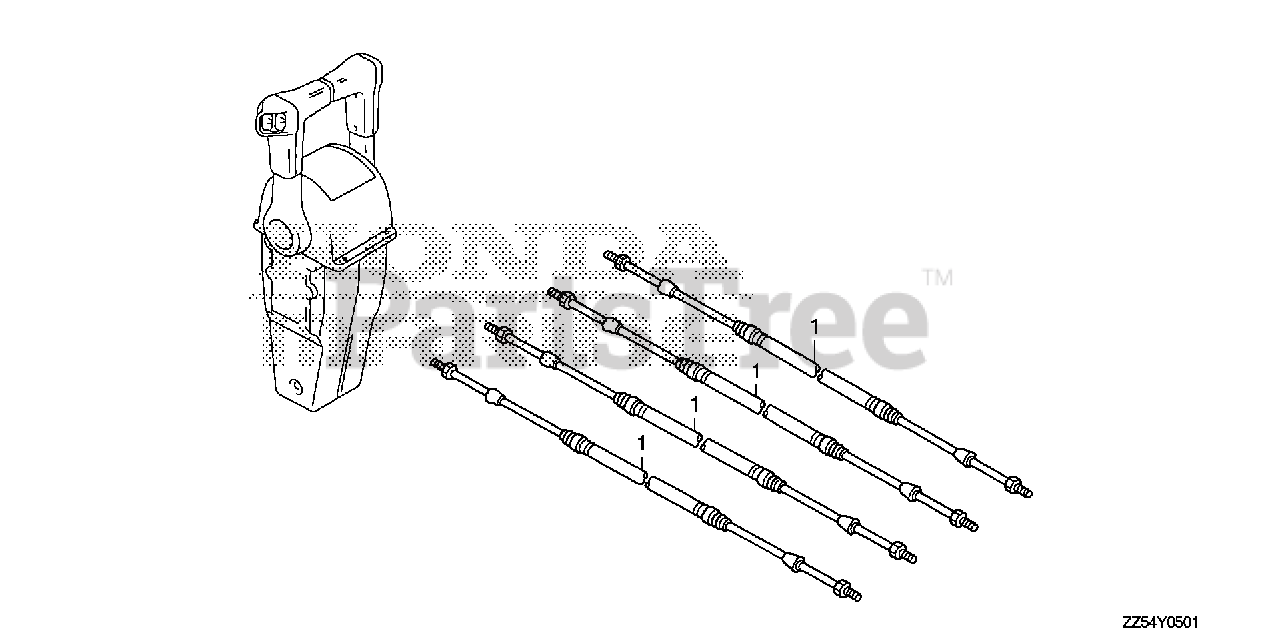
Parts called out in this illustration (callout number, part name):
1	CABLE, REMOTE CONTROL (10') (LOW FRICTION)
1	CABLE ASSY., PUSH-PULL (33C-5FT)
1	CABLE, REMOTE CONTROL (11') (LOW FRICTION)
1	CABLE ASSY., PUSH-PULL (33C-6FT)
1	CABLE, REMOTE CONTROL (12') (LOW FRICTION)
1	CABLE ASSY., PUSH-PULL (33C-7FT)
1	CABLE, REMOTE CONTROL (13') (LOW FRICTION)
1	CABLE ASSY., PUSH-PULL (33C-8FT)
1	CABLE, REMOTE CONTROL (14') (LOW FRICTION)
1	CABLE ASSY., PUSH-PULL (33C-9FT)
1	CABLE, REMOTE CONTROL (15') (LOW FRICTION)
1	CABLE ASSY., PUSH-PULL (33C-10FT)
1	CABLE, REMOTE CONTROL (16') (LOW FRICTION) (NOT AVAILABLE)
1	CABLE ASSY., PUSH-PULL (33C-11FT)
1	CABLE, REMOTE CONTROL (17') (LOW FRICTION)
1	CABLE ASSY., PUSH-PULL (33C-12FT)
1	CABLE, REMOTE CONTROL (18') (LOW FRICTION) (NOT AVAILABLE)
1	CABLE ASSY., PUSH-PULL (33C-13FT)
1	CABLE, REMOTE CONTROL (19') (LOW FRICTION)
1	CABLE ASSY., PUSH-PULL (33C-14FT)
1	CABLE, REMOTE CONTROL (20') (LOW FRICTION) (NOT AVAILABLE)
1	CABLE ASSY., PUSH-PULL (33C-15FT)
1	CABLE, REMOTE CONTROL (21') (LOW FRICTION)
1	CABLE ASSY., PUSH-PULL (33C-16FT)
1	CABLE, REMOTE CONTROL (22') (LOW FRICTION) (NOT AVAILABLE)
1	CABLE ASSY., PUSH-PULL (33C-17FT)
1	CABLE, REMOTE CONTROL (23') (LOW FRICTION)
1	CABLE ASSY., PUSH-PULL (33C-18FT)
1	CABLE, REMOTE CONTROL (24') (LOW FRICTION) (NOT AVAILABLE)
1	CABLE ASSY., PUSH-PULL (33C-19FT)
1	CABLE, REMOTE CONTROL (25') (LOW FRICTION)
1	CABLE ASSY., PUSH-PULL (33C-20FT)
1	CABLE, REMOTE CONTROL (26') (LOW FRICTION)
1	CABLE ASSY., PUSH-PULL (33C-21FT)
1	CABLE, REMOTE CONTROL (27') (LOW FRICTION)
1	CABLE ASSY., PUSH-PULL (33C-22FT)
1	CABLE, REMOTE CONTROL (28') (LOW FRICTION) (NOT AVAILABLE)
1	CABLE ASSY., PUSH-PULL (33C-23FT)
1	CABLE, REMOTE CONTROL (29') (LOW FRICTION)
1	CABLE ASSY., PUSH-PULL (33C-24FT)
1	CABLE, REMOTE CONTROL (30') (LOW FRICTION) (NOT AVAILABLE)
1	CABLE ASSY., PUSH-PULL (33C-25FT)
1	CABLE, REMOTE CONTROL (31') (LOW FRICTION)
1	CABLE ASSY., PUSH-PULL (33C-26FT)
1	CABLE, REMOTE CONTROL (32') (LOW FRICTION) (NOT AVAILABLE)
1	CABLE ASSY., PUSH-PULL (33C-27FT)
1	CABLE, REMOTE CONTROL (33') (LOW FRICTION)
1	CABLE ASSY., PUSH-PULL (33C-28FT)
1	CABLE, REMOTE CONTROL (34') (LOW FRICTION) (NOT AVAILABLE)
1	CABLE ASSY., PUSH-PULL (33C-29FT)
1	CABLE, REMOTE CONTROL (35') (LOW FRICTION)
1	CABLE ASSY., PUSH-PULL (33C-30FT)
1	CABLE ASSY., PUSH-PULL (33C-31FT)
1	CABLE ASSY., PUSH-PULL (33C-32FT)
